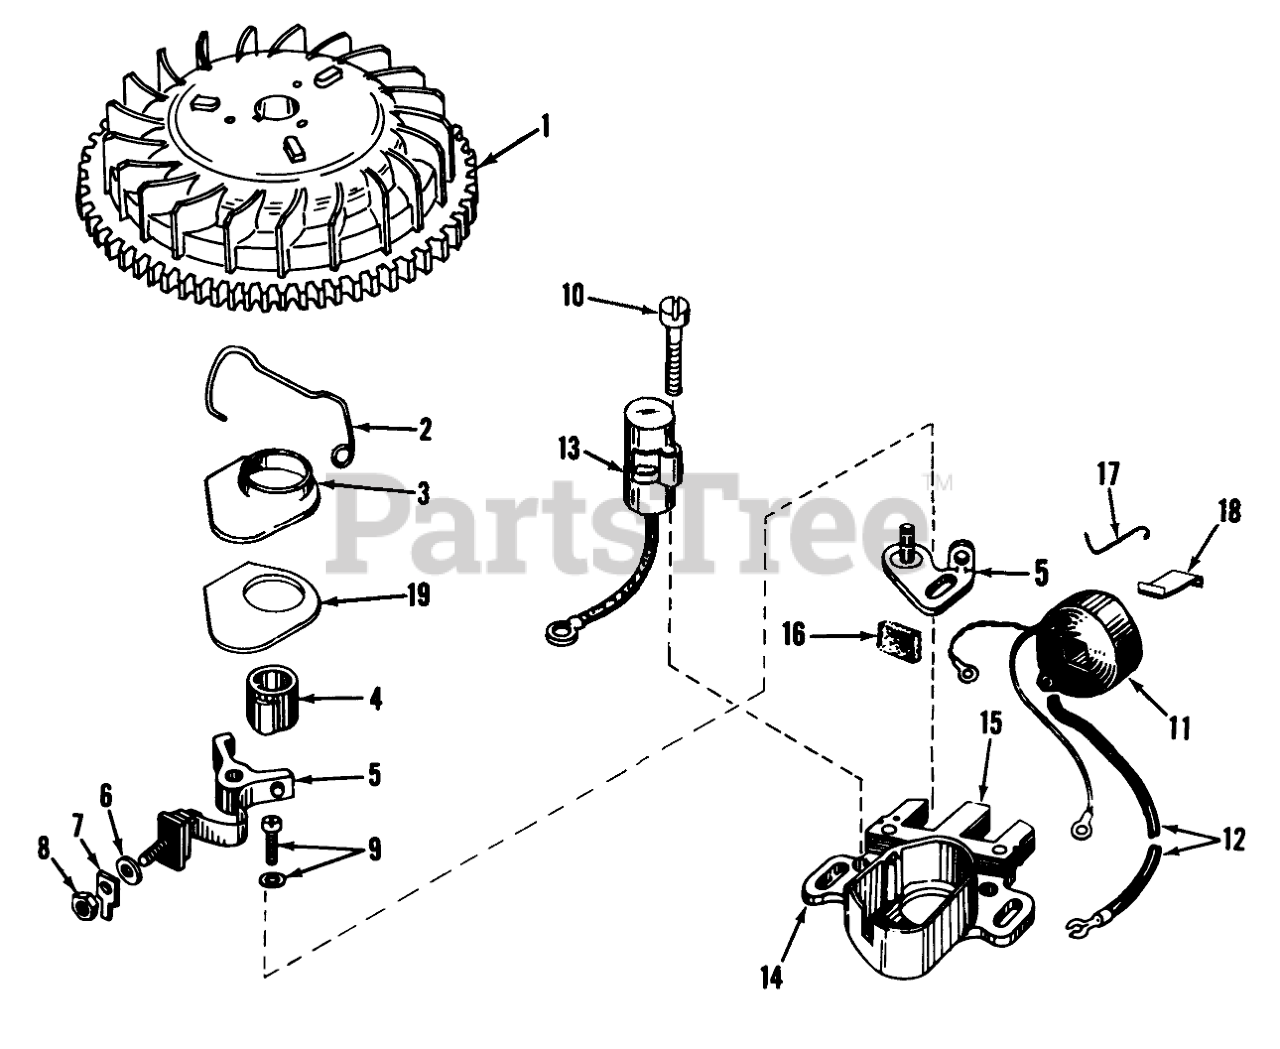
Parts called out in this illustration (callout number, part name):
1	Flywheel
2	Spring Breaker Box
3	Cover, Dust
4	Cam-Breaker
5	Breaker Assy.
6	Washer
7	Terminal, Ground
8	DECAL
9	Breaker Screw
10	Condenser Screw
11	Coil Assy. (Incl. No. 12)
12	Wire, Lead
13	Condenser
14	Core & Plate
15	Stator Assy. (Incl. Nos. 2, 3, 5 thru 14 & 16 thru 19)
16	Felt,Cam Wiper
17	Clip, Coil
18	Spring Coil Wedge
19	Gasket Dust Cover
